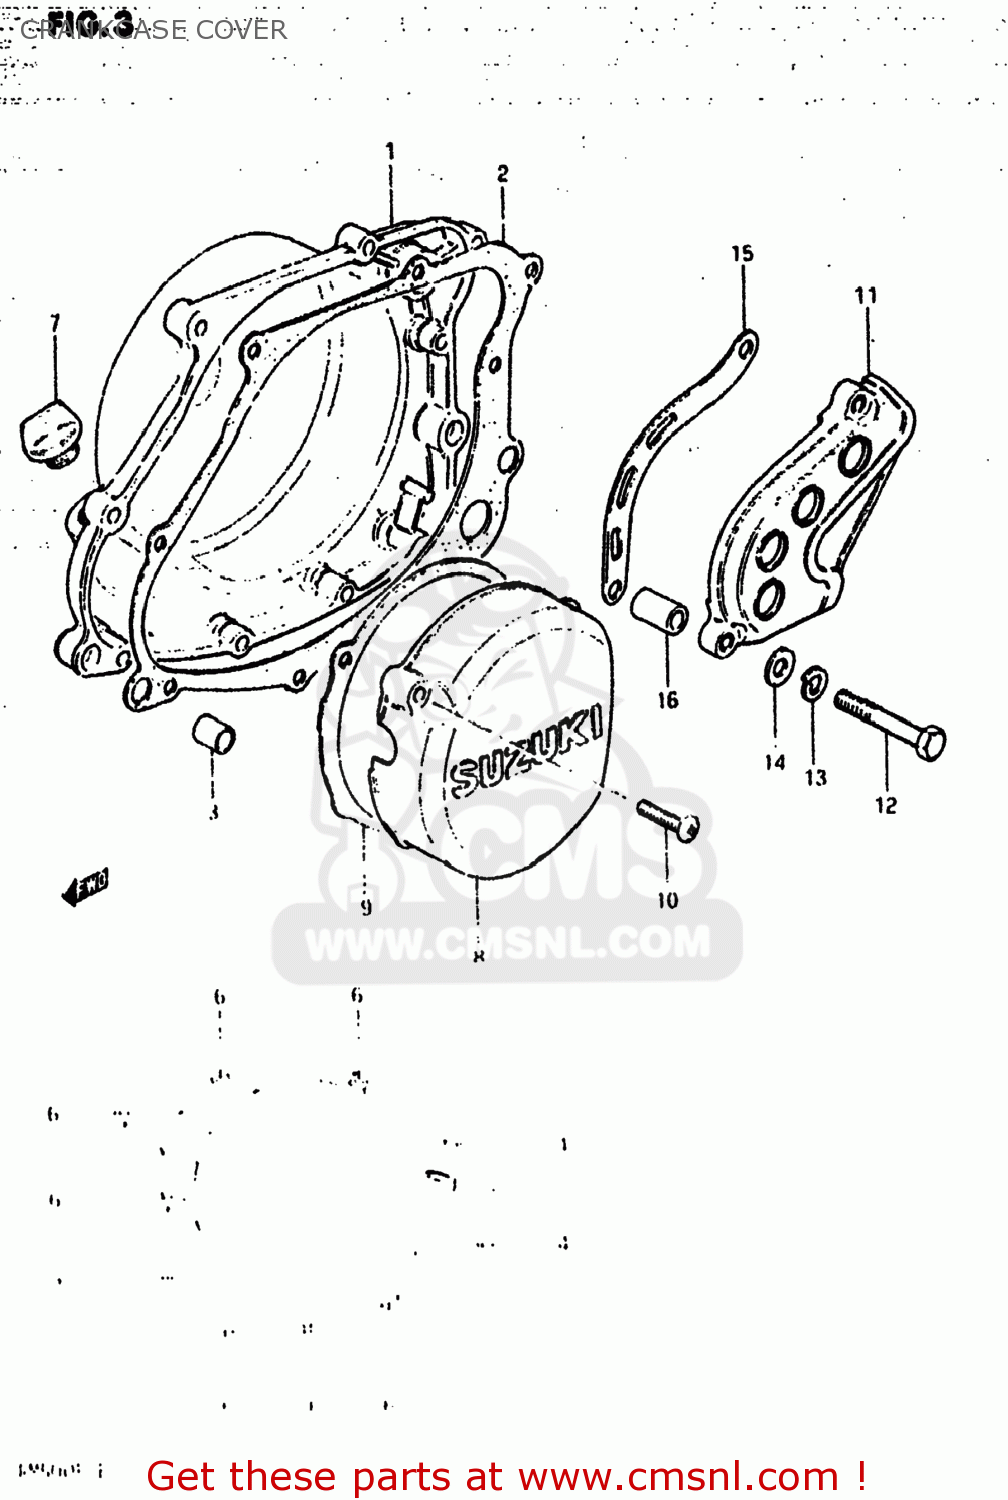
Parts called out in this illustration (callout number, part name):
1	COVER,CLUTCH
2	GASKET,CLUTCH COVER (MCA)
3	PIN
4	SCREW
5	SCREW
6	SCREW
7	PLUG,OIL FILTER
8	COVER,MAGNETO
9	GASKET,MAGNETO COVER (MCA)
10	SCREW
11	COVER,ENGINE SPROCKET
12	BOLT 8X55
13	LOCK WASHER
14	WASHER,8.5X16X
15	PLATE,FR CHAIN GUIDE
16	SPACER(8.6X16X24)
